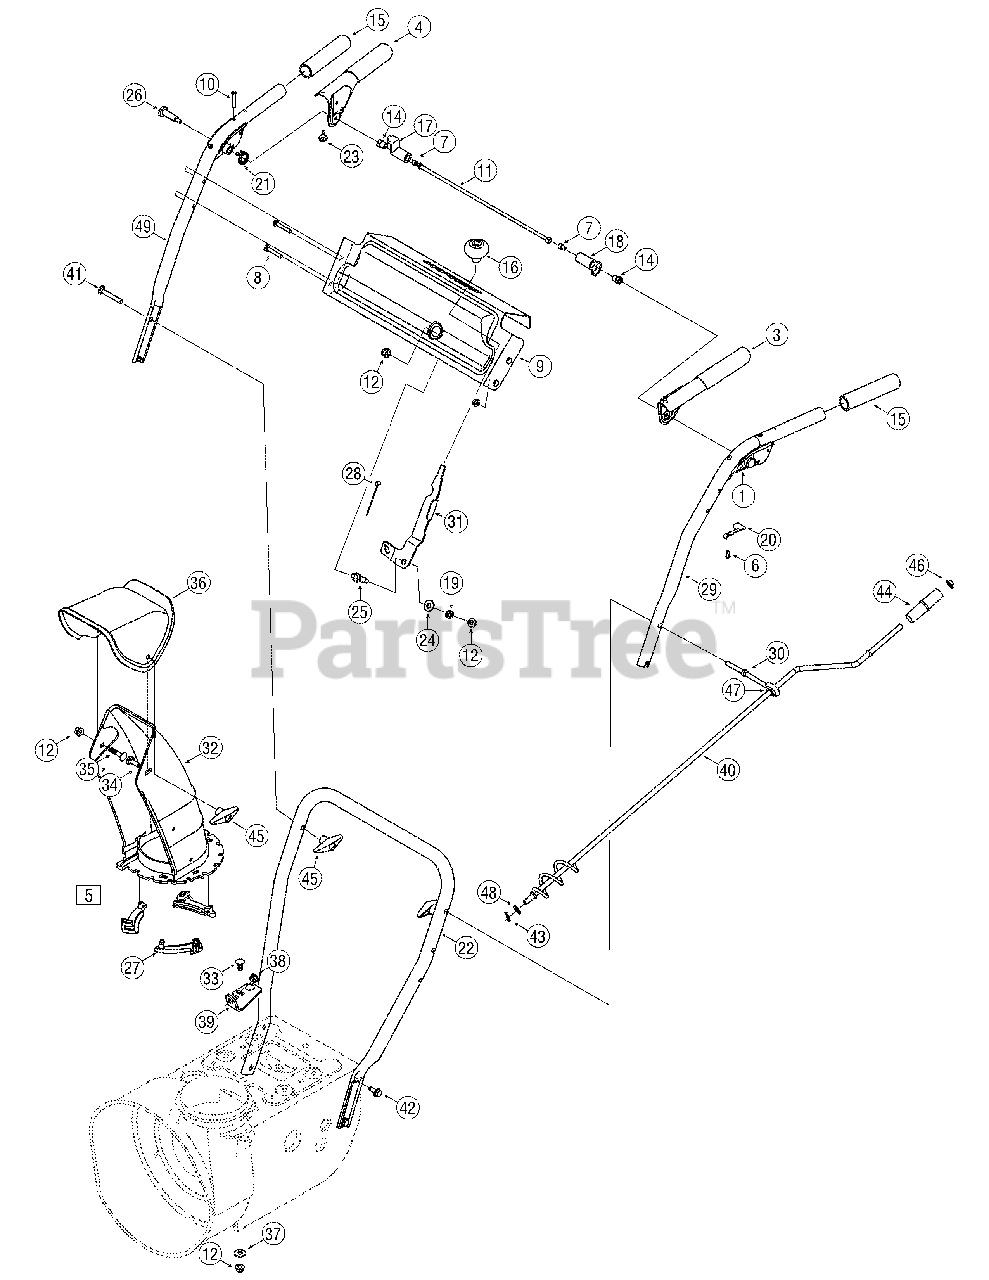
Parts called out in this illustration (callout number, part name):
1	Handle Assembly, Clutch Lock, LH
2	Handle Assembly, Clutch Lock, RH
3	Handle Ass’y, Engage, Black, LH
4	Handle Ass’y, Engage, Black, RH
5	Chute Assembly (Includes Ref. # 27)
6	Screw, #8-16 x .50
7	Screw, 1/4-20, .375
8	Hex Screw, 1/4-20, 1.50, Gr5
10	Screw, Machine, #10-24, 1.375
11	Pivot Rod
12	Nut, Flange Lock, 5/16-18, Nylon
13	Nut, Flange Lock, 1/4-20, Nylon
14	Nut, Hex, 1/4-20, Shoulder
15	Grip, 1.0 ID x 5.0
16	Knob, Shift, Black
17	Lock Plate
18	Cam, Clutch Lock
19	Spring, .39 x .60 x .88
20	Spring, Clutch Lock
21	Spring, Torsion, 0.8156 ID x .3038
23	Bumper, Rubber, .62 OD x .22
24	Washer, Flat, .385 x .870 x .092
25	Bolt, Shoulder, 5/16-18 x 0.905
26	Screw, Shoulder, .43 x 1.3, 1/4-20
27	Chute, Flange Keeper
28	Cable, Speed Selector
30	Eye Bolt, Chute Crank
32	Chute, Lower, 5.0 Dia.
33	Bolt, Carriage, 5/16-18, 1.0
34	Bolt, Carriage, 5/16-18, 1.0
35	Bolt, Carriage, 5/16-18, .750
36	Chute, Upper, w/ Label
37	Washer, .349 x .879 x .063
38	Bushing, Plastic, .380
41	Screw, Carriage, 5/16-18, 2.25
42	Screw, 5/16-18, 2.25, Gr5
43	Pin, Cotter, .072 x 1.13
44	Crank Knob, 1.0 Dia. x 3.2, Black
45	Knob, 5/16-18, Black
46	Cap, Push, 3/8 Rod
47	Grommet, .44 ID x .94 OD x .50
48	Washer, Flat, .375 x .738 x .063
